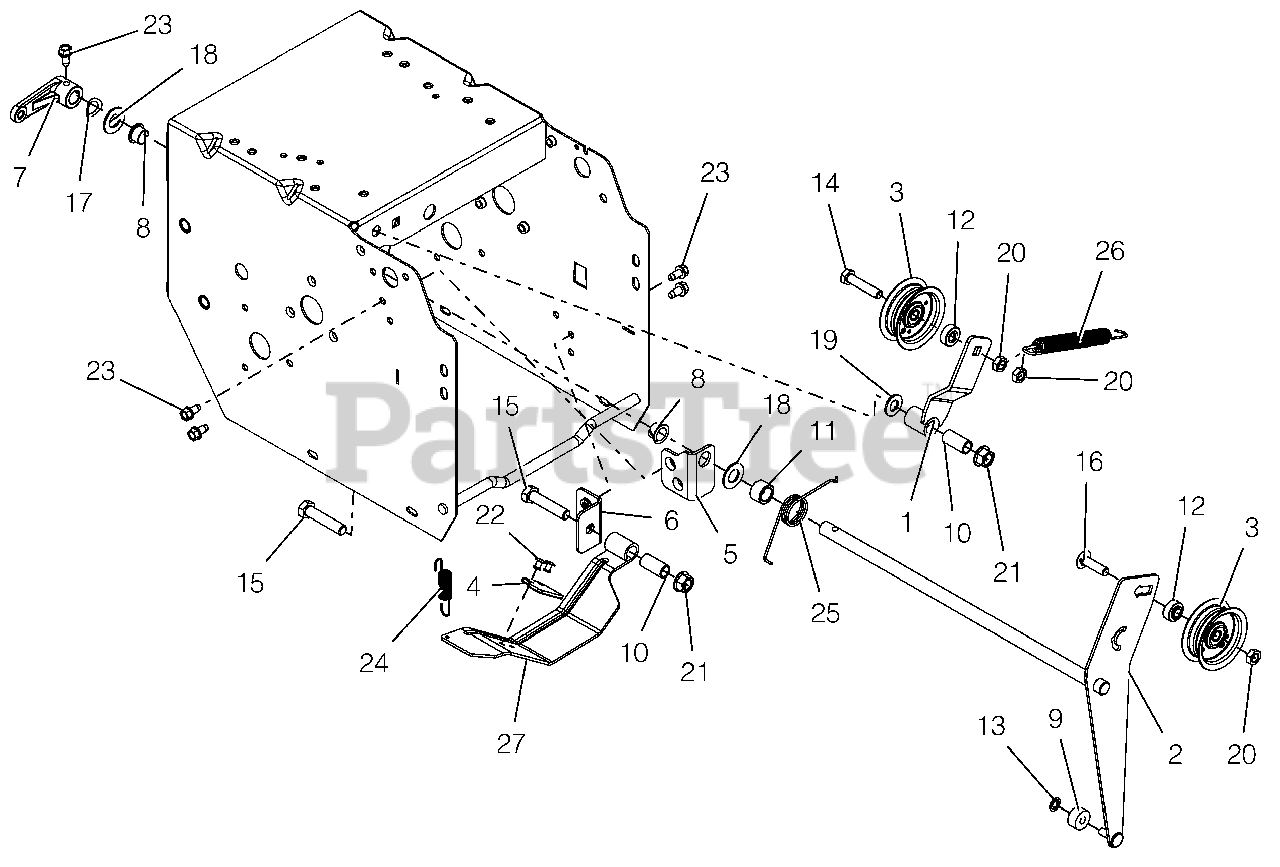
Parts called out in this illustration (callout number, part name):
1	ARM, TRACTION IDLER
2	WELDMENT, ATTACHMENT IDLER ARM
3	IDLER, FLAT - 2.00"
4	PAD, BRAKE
5	BRACKET, MOUNT - IDLER ARM
6	BRACKET, MOUNT - BRAKE
7	ARM, CLUTCH - ATTACHMENT
8	BUSHING, POLYLINER-.50 SPLIT
9	BSHG,SLV .265 X .625 X .375
10	BSHG-SLV .385X.500X1.045
11	BSHG-SLV .510X.751X.475
12	SPCR, BRG .315X.500X.358X.281
13	RG-RTNG-EXT .250X.010
14	@BLT-HEX .31-18X1.50 GR5 YWZC
15	@BLT-HEX .38-16X1.75 GR5 YWZC
16	BLT-RDHDSQSHNK.31-18X1.13 G5YZ
17	WSHR-WAVE .50X.75X.015 .13FRHT
18	WSHR-FL-STL.531X1.00X.063 YWZC
19	@WSHR-FL-STL.406X.812X.065 YWZ
20	@NUT-LK-CTR-JAM .31-18 YWZC
21	@NUT-LK-TOP-FLG .38-16 YWZC
22	RVT-POP .187 YZ
23	SCR-TAP .25-20X.50 HWH TR YWZ
24	SPRING-EXT .437 X .438 X 2.64
25	SG-TORS .075 X .955
26	SPRING, SWIVEL HOOK EXTENSION
27	BRAKE ARM W/PAD
